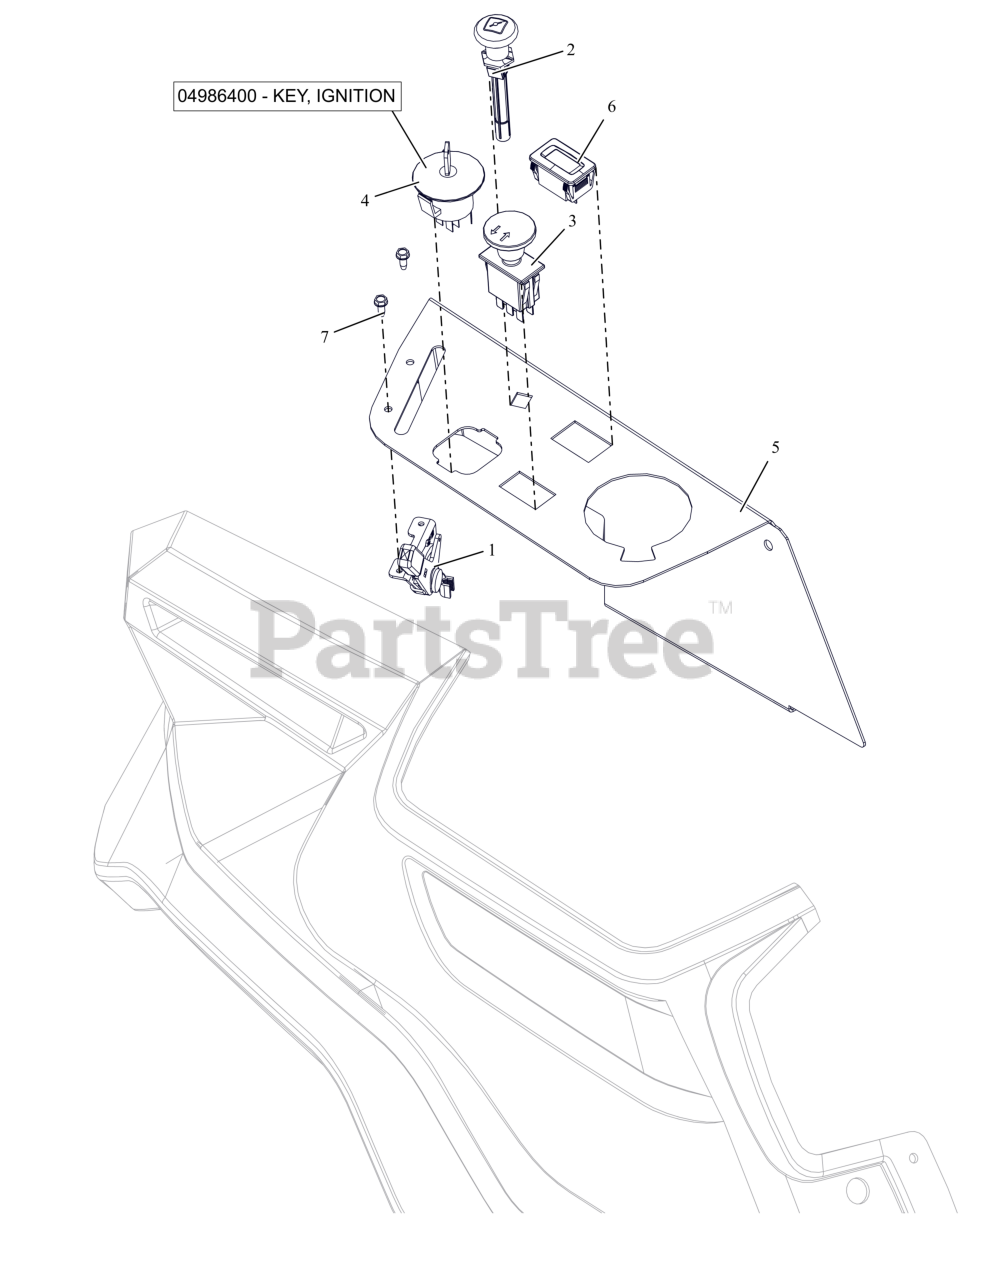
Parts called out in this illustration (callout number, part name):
1	CABLE - THROTTLE CONTROL
2	CABLE - CHOKE, SNAP-IN
3	SWITCH, CLUTCH (YELLOW)
4	KEYSWITCH-IGNITION 4 POS
4	KEY, IGNITION
5	PANEL, RIGHT SIDE FENDER MOUNT
6	HOUR METER
7	SCR,TAP #10-24X.50 HWH TR ZCC
